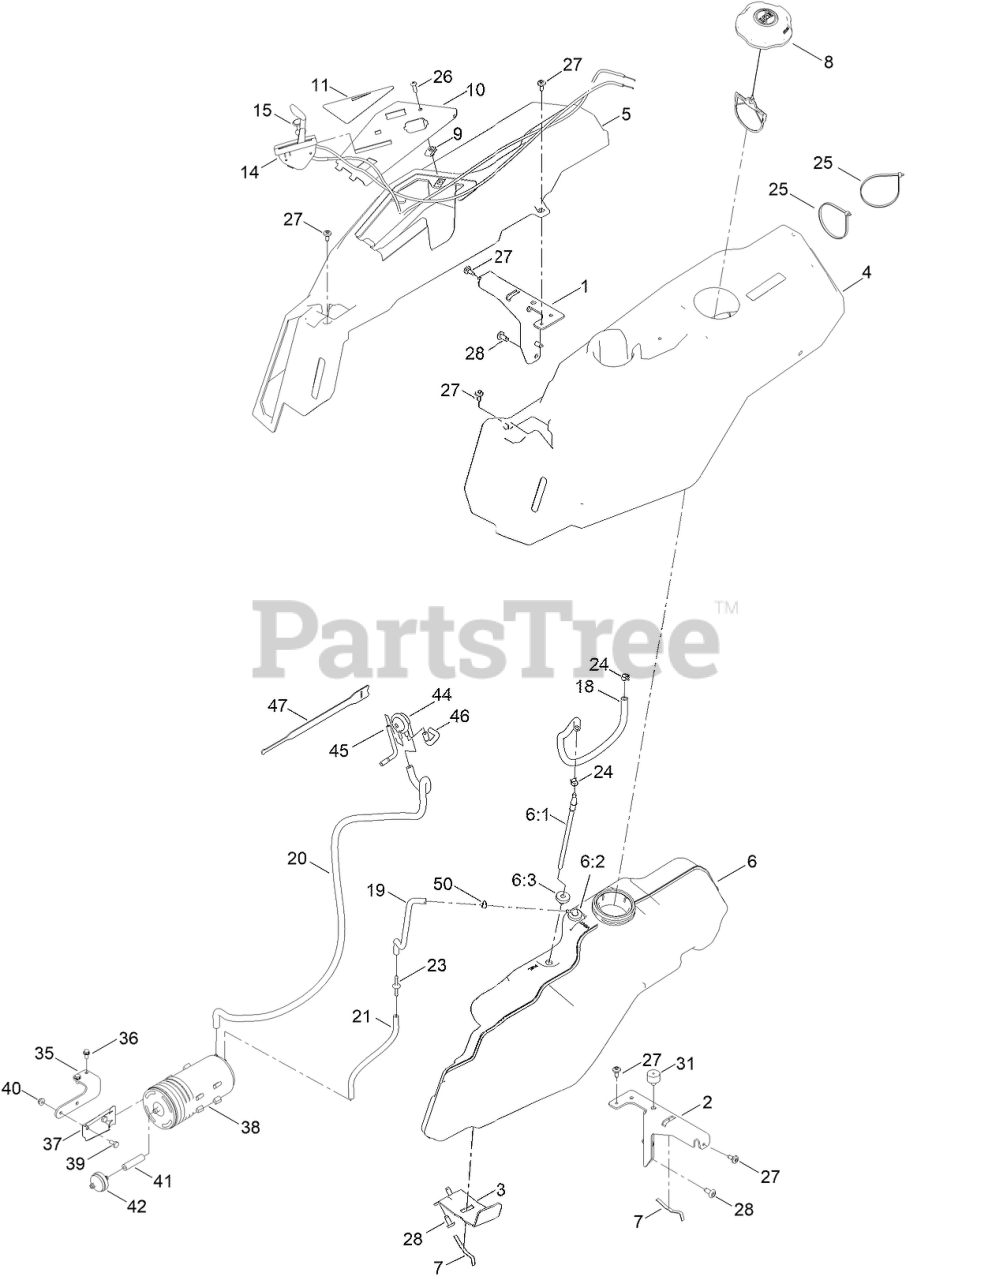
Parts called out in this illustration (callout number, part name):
1	SUPPORT-POD, RH
2	SUPPORT-POD, LH
3	SUPPORT-TANK, FUEL
4	POD-LH
5	POD-RH
6	TANK-FUEL ASM
6:1	CONNECTOR-ELBOW, 90 DEG
6:2	FITTING-ELBOW 90
6:3	BUSHING
7	SPRING
8	CAP-FUEL, RATCHETING
10	PANEL - CONTROL
11	DECAL-PANEL, CONTROL
14	CABLE-THROTTLE
15	CABLE-CHOKE
18	HOSE-FUEL
19	HOSE-FUEL
20	HOSE-FUEL
21	HOSE-FUEL
23	ADAPTER ORIFICE
24	CLAMP-HOSE
25	TIE-CABLE
26	SCREW-PRH
27	SCREW-SHOULDER
31	BUMPER-GROMMET
35	BRACKET-CANISTER, CARBON
36	SCREW-HWH
37	BRACKET-CANISTER, CARBON
38	CANISTER-CARBON, 800CC
39	SCREW-HH
40	NUT-HF
41	HOSE-FUEL
42	FILTER-FUEL, INLINE
44	VALVE-CONTROL, VACUUM
45	HOSE-VENT, FORMED
46	HOSE-VENT, FORMED
47	STRAP-VELCRO, CABLE TIE
50	CLAMP-HOSE
